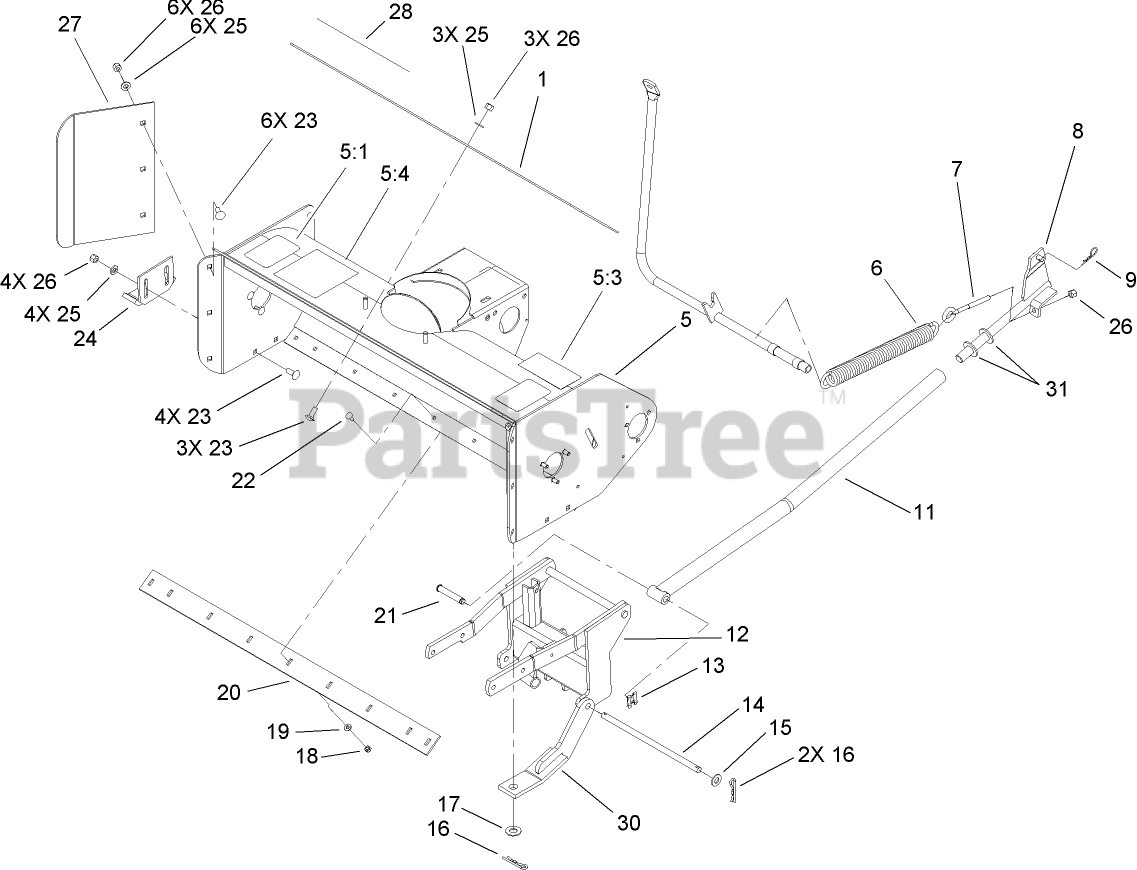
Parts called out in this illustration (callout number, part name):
1	PLATE-EXTENSION
5	WRAPPER ASM W/DECAL
5:1	DECAL-DANGER
5:3	DECAL - WARNING
5:4	DECAL-WARNING
6	SPRING-EXTENSION
7	EYEBOLT
9	PIN-HAIR
12	FRAME ASM
13	CLIP-PIN
14	ROD-SUPPORT
15	WASHER-FLAT
16	PIN-COTTER, HAIR
17	WASHER-FLAT
18	NUT-LOCK, NI
19	WASHER-FLAT
21	PIN-CLEVIS
23	BOLT-CARR
25	WASHER-FLAT
26	NUT-LOCK, NI
27	PLATE-EXTENSION, RH
28	DECAL-WORKHORSE
30	LINK ASM
31	WASHER-FLAT
